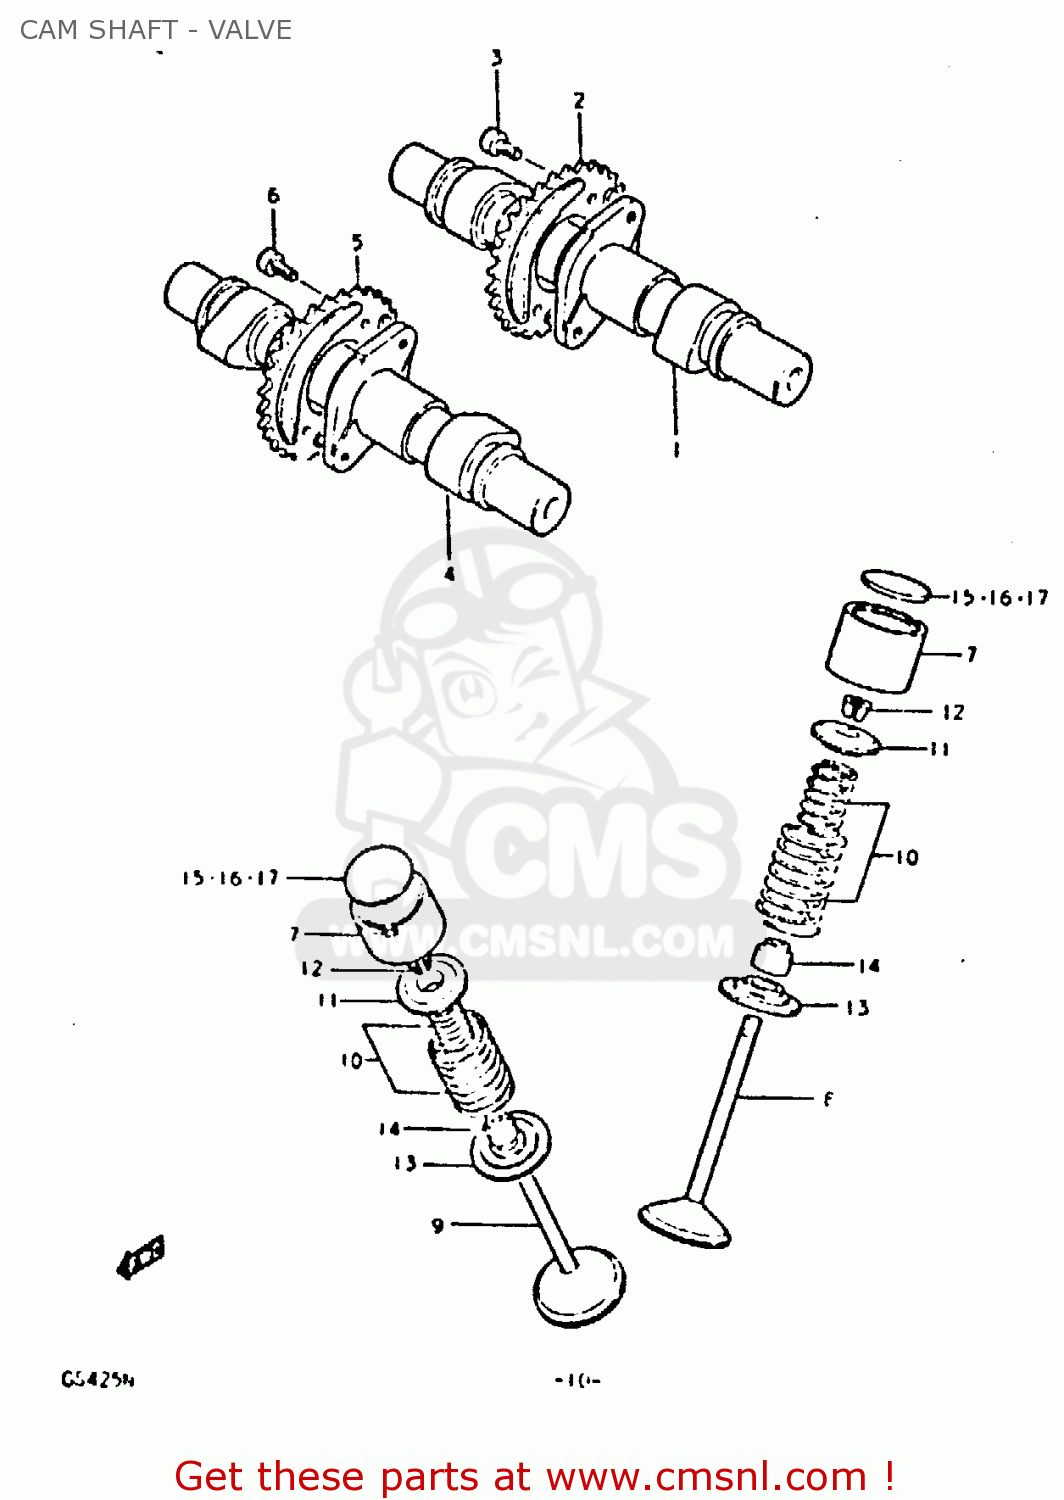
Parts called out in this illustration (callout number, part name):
1	CAMSHAFT
2	SPROCKET,CAMSHAFT
3	BOLT 6X11
4	CAMSHAFT,EXHAUST
5	SPROCKET,EXHAUST CAMSHAFT
6	BOLT 6X11
7	TAPPET
8	VALVE,INTAKE
9	VALVE,EXHAUST
10	SPRING SET,VALVE
11	RETAINER,VALVE SPRING
12	SHIM,TAPPET
13	SEAT,VALVE SPRING
14	SEAL,OIL(7X14.4X9)
15	SHIM,TAPPET
16	SHIM,TAPPET
17	SHIM,TAPPET
